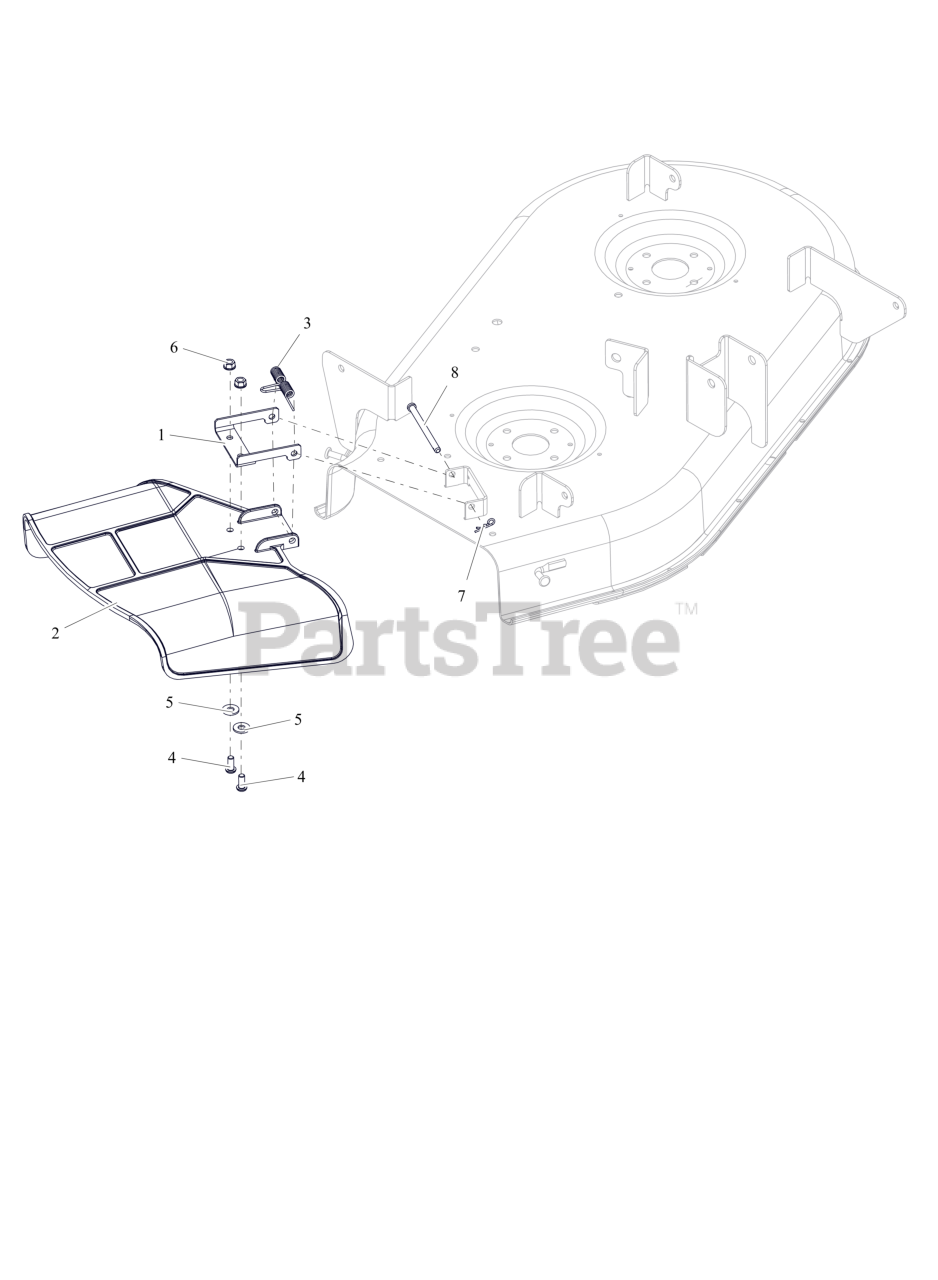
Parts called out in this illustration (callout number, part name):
1	CHUTE, REINFORCEMENT (ORANGE)
2	CHUTE, SIDE DISCHARGE
3	SPRING, TORSION
4	SCR-SKH .31-18X.75 BTNHD YWZC
5	WSHR,FLT .375X.875X.083 ZCC
6	NUT,LK-CTR-FLG .31-18 GF ZCC
7	PIN, HAIR #213 .08X1.19 ZCC
8	PIN, 5/16 X 3.88"
